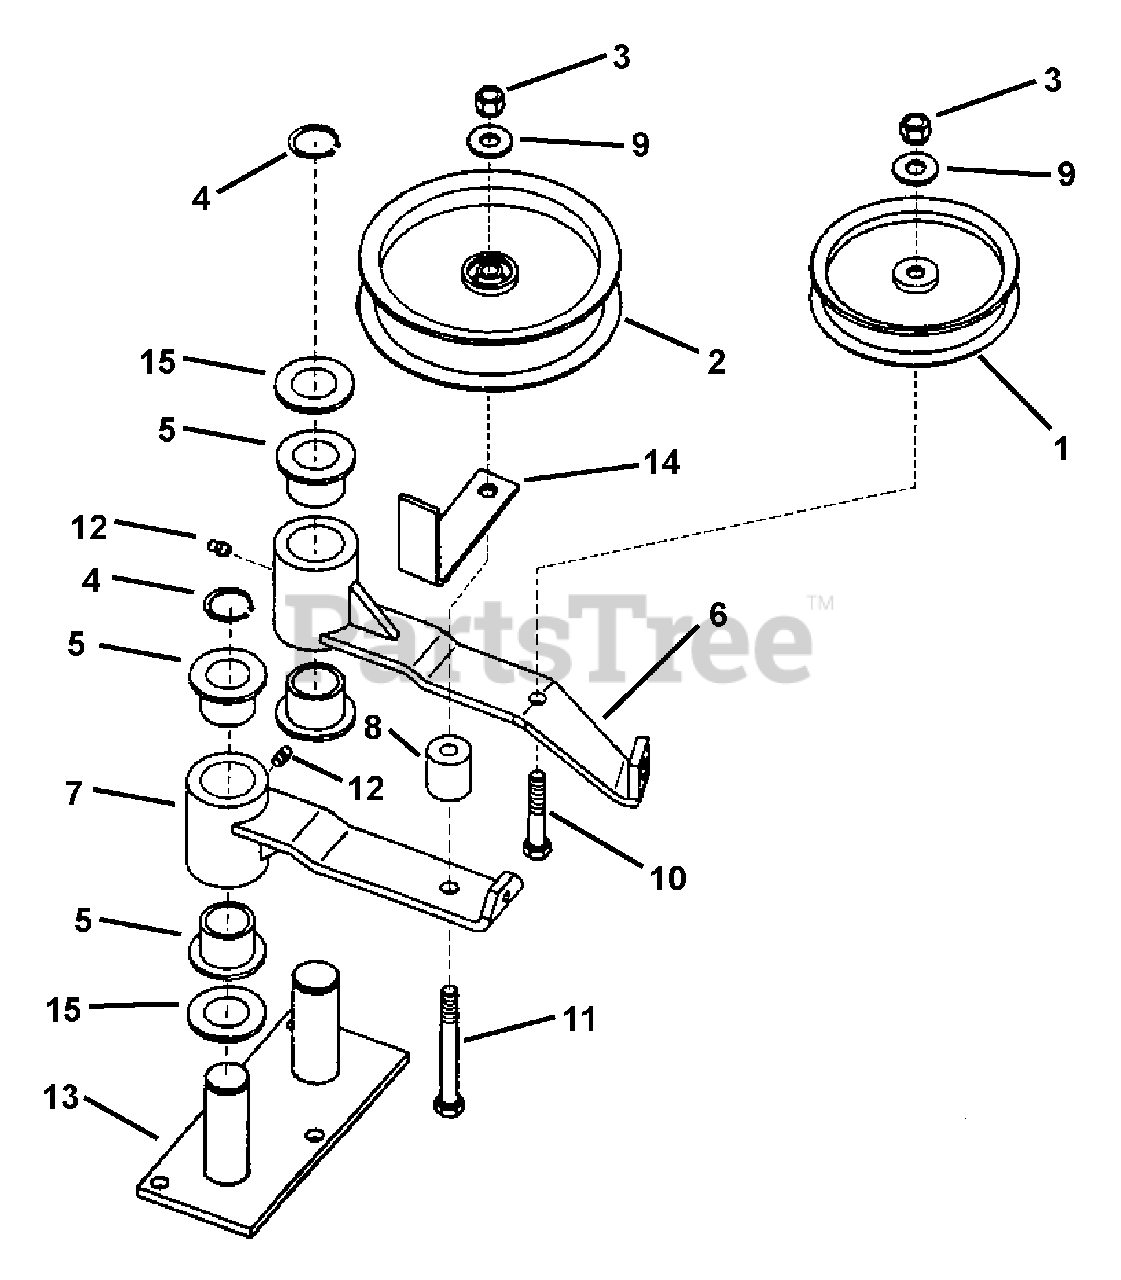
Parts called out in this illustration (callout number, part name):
1	PULLEY, Idler
2	PULLEY, Flat Idler 5" O.D.
3	NUT, 3/8-16 HEX NYLON LOCK
4	RING, 1" Retaining
5	BUSHING
6	IDLER ARM
7	IDLER ARM
8	SPACER, Idler Pulley
9	WASHER, 3/8" USS
10	BOLT, 3/8-16 X 2, GD5, CZ
11	BOLT, 3/8-16 x 3-1/4" Hex Head Cap, Grade 5
12	FITTING, Lube
13	PIVOT, Idler
14	RETAINER, Belt
